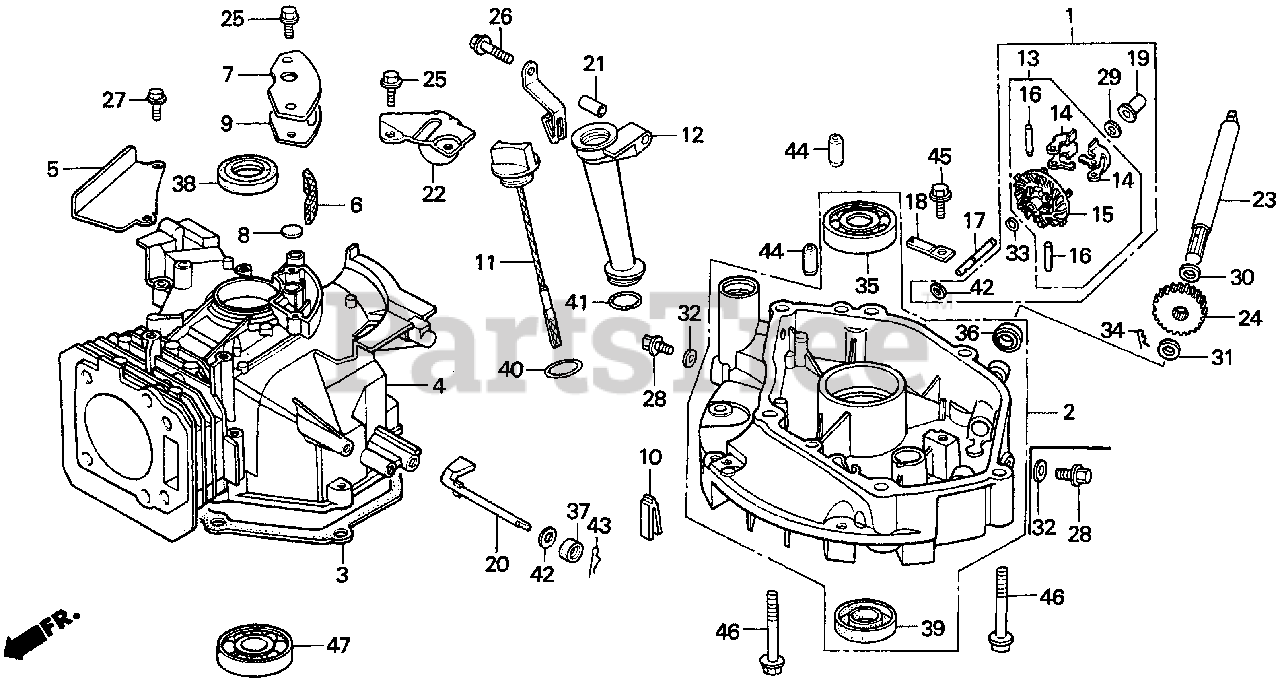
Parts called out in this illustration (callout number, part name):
1	GOVERNOR KIT
2	PAN ASSY., OIL
3	GASKET, OIL PAN
4	CYLINDER ASSY.
5	PLATE, GUIDE
6	FILTER, BREATHER
7	COVER, BREATHER
8	VALVE, BREATHER
9	GASKET, BREATHER COVER
10	RUBBER, OIL RETURN
11	DIPSTICK, OIL
12	EXTENSION, OIL FILLER (NOT AVAILABLE)
12	EXTENSION, OIL FILLER
13	GOVERNOR ASSY.
14	WEIGHT, GOVERNOR
15	HOLDER, GOVERNOR WEIGHT
16	PIN, GOVERNOR WEIGHT
17	SHAFT, GOVERNOR HOLDER
18	PLATE, GOVERNOR SHAFT HOLDER
19	SLIDER, GOVERNOR
20	SHAFT, GOVERNOR ARM
21	COLLAR, EXTENSION
22	STAY, TANK
23	SHAFT, DRIVE
24	GEAR, DRIVEN (22T)
25	BOLT, FLANGE (6X14) (CT200)
26	BOLT, FLANGE (6X32) (CT200)
27	BOLT, FLANGE (6X20) (CT200)
28	BOLT, DRAIN PLUG
29	WASHER, THRUST (6MM)
30	WASHER, THRUST (12MM)
31	WASHER (10X21)
32	WASHER, DRAIN PLUG (10.2MM)
33	CLIP, GOVERNOR HOLDER
34	PIN, LOCK (2.0)
35	BEARING, RADIAL BALL
36	OIL SEAL (12X20X5) (ARAI)
37	OIL SEAL (6X11X4) (ARAI)
38	OIL SEAL (25X38X7)
38	OIL SEAL (25X38X7) (ARAI)
39	OIL SEAL (25.4X40X7)
40	O-RING (26X2.7)
41	O-RING (22.1X2.2)
41	O-RING (22.1X2)
42	WASHER, PLAIN (6MM)
43	PIN, LOCK (8MM)
44	PIN, DOWEL (8X14)
45	BOLT, FLANGE (6X12)
46	BOLT, FLANGE (8X50)
47	BEARING, RADIAL BALL (6205)
